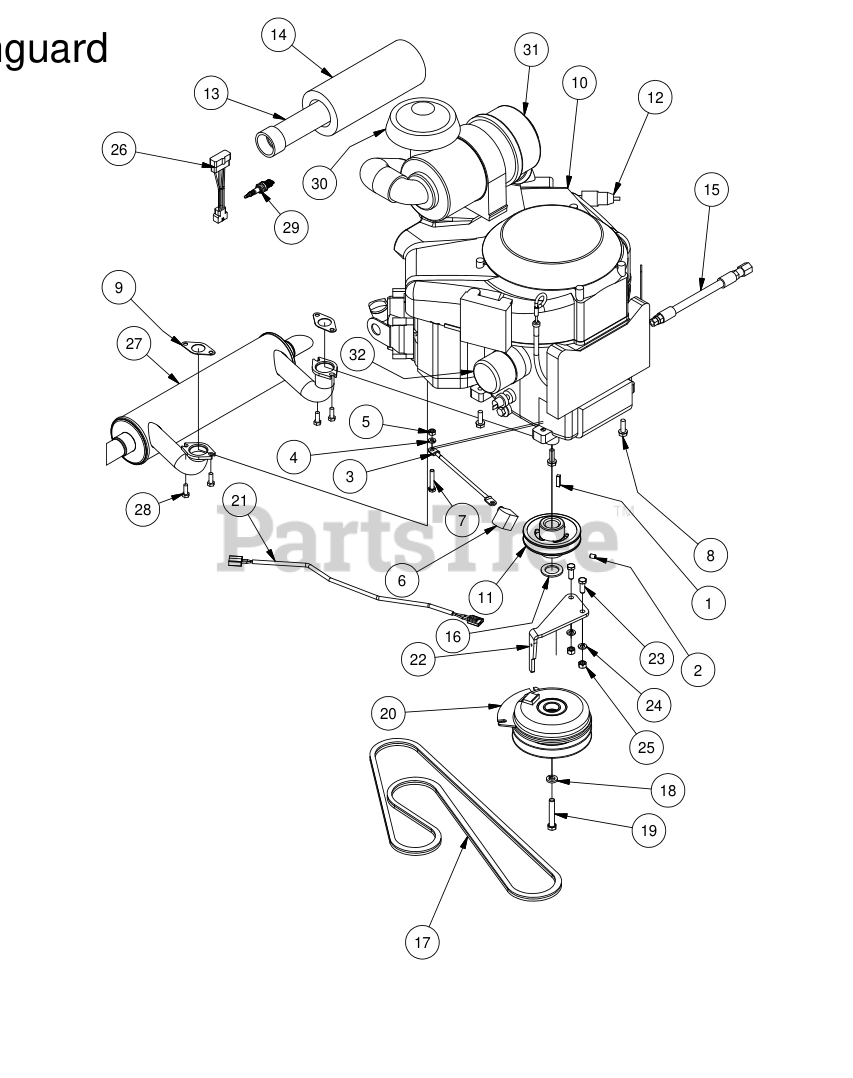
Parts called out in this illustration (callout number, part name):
1	1/4" x 1" Key
2	5/16 Set Screw
3	Ground Cable
4	5/16" Lock Washer
6	Black Boot For Ground Cable
7	5/16" x 1 3/4" Hex Bolt
8	3/8 x 1 1/8 bolt
9	Exhaust Gasket for 23 Vanguard
10	993cc Briggs Vanguard Engine
11	4 3/4 Motor Pulley
12	Universal Inline Fuel Filter
13	Canister Air Filter- Inner
14	Canister Air Filter- Outer
15	14 mm Oil drain Hose 993cc Vanguard
16	1 1/8" Flat Spacer
18	7/16" Lock Washer
19	7/16" x 2 1/2" Hex Bolt
20	Clutch Assembly
21	Clutch Pigtail
22	PTO Engager Holder
23	3/8" x 1" Hex Bolt
24	3/8" Lock Washer
25	3/8" Hex Nut
26	Harness Adaptor - 933cc Vanguard
27	2015 Exhaust - 36hp Vanguard
28	Torx Bolt-Exhaust
29	Spark Plug
30	Rain Cap Fits all Canisters
31	Complete Canister
32	Briggs Oil Filter
